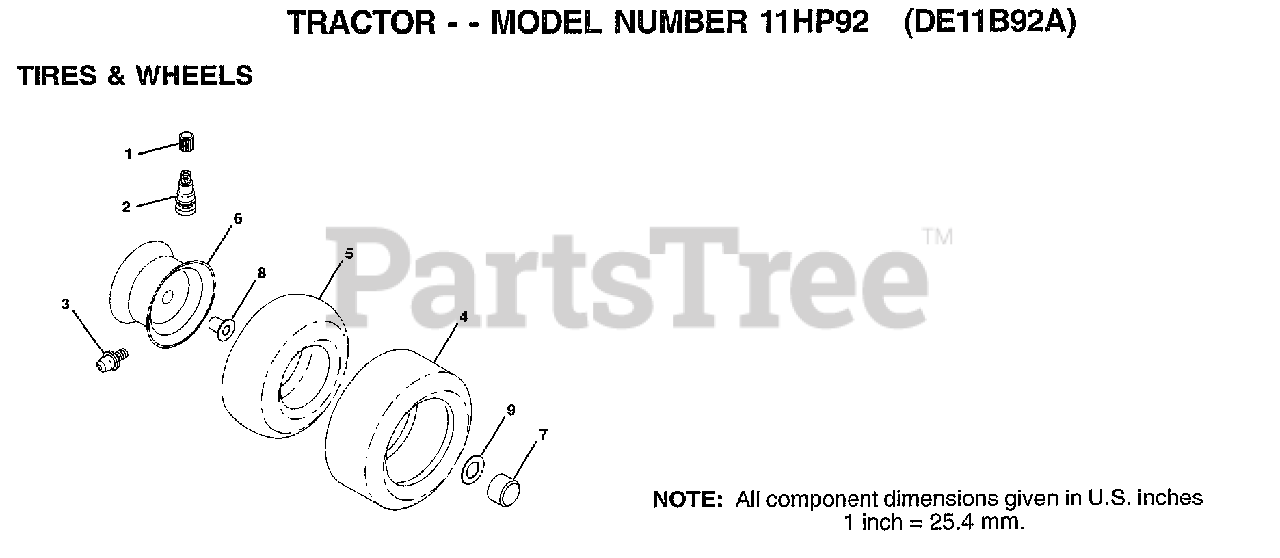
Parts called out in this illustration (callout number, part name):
1	VALVE CAP
2	VALVE STEM LT
3	FITTING LT
5	TUBE.5.3/4.5/6
5	TUBE.16X6.5/7.5-8
6	"RIM.FRT.6"".ASM"
6	"RIM REAR 8"""
7	HUB CAP
8	"FLANGE, BEARING"
9	WASHER
